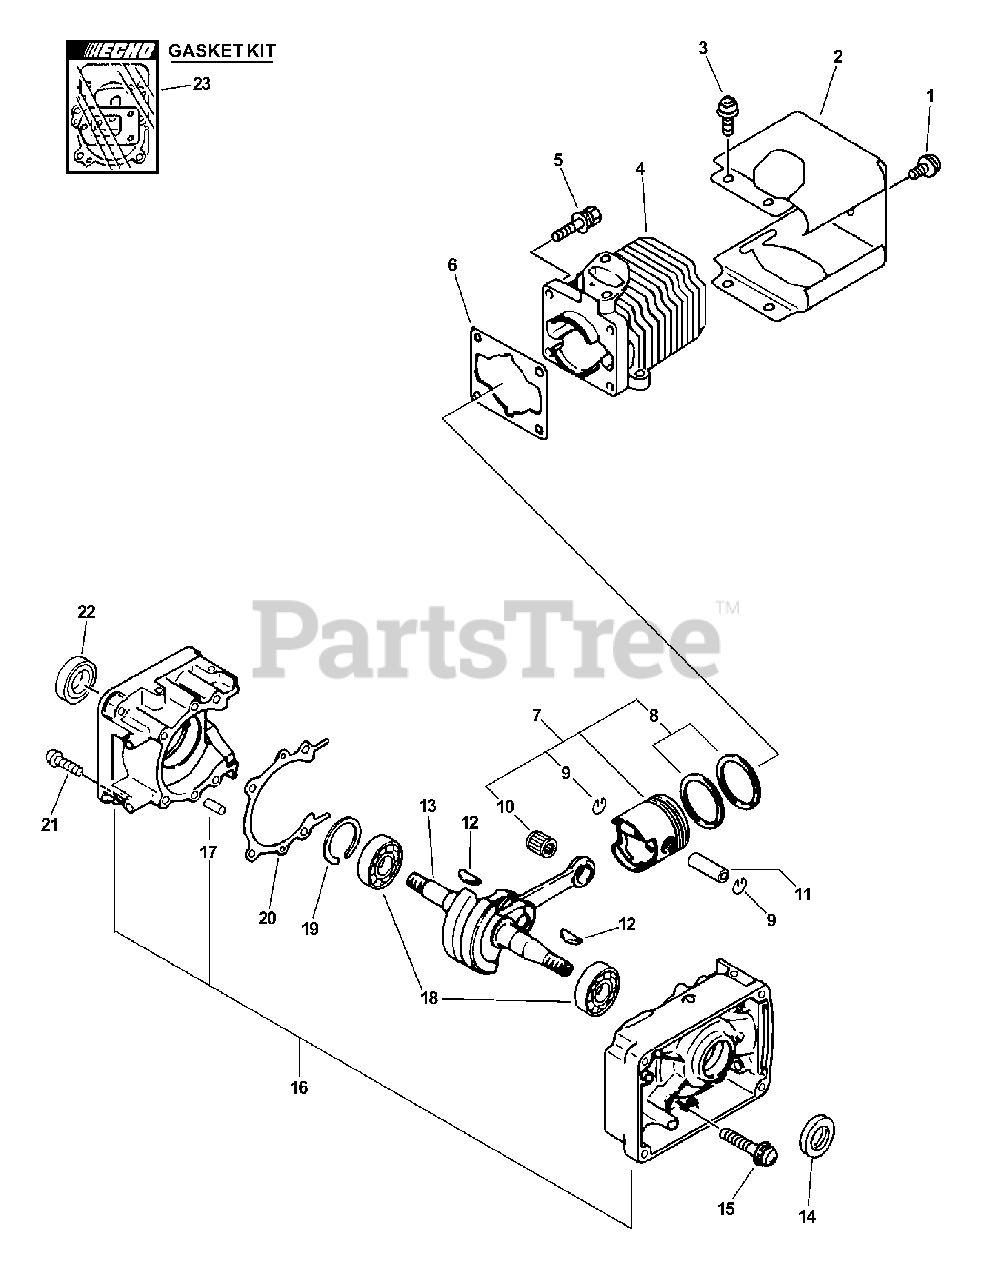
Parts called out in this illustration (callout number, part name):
1	SCREW 5×10
2	COVER, CYLINDER
3	SCREW 4×10
4	CYLINDER
5	BOLT 5×20
6	GASKET, CYLINDER
7	PISTON KIT
8	RING, PISTON
9	RING, SNAP
10	BEARING, NEEDLE
11	PIN, PISTON
12	KEY, WOODRUFF 3×14
13	CRANKSHAFT
14	SEAL, OIL 12
15	SCREW 5×30
16	CRANKCASE KIT
17	PIN, LOCATING 4
18	BEARING, BALL - 6201 C3
19	RING, SNAP Ø32
20	GASKET, CRANKCASE
21	SCREW 5×20
22	SEAL, OIL 12
23	GASKET KIT
